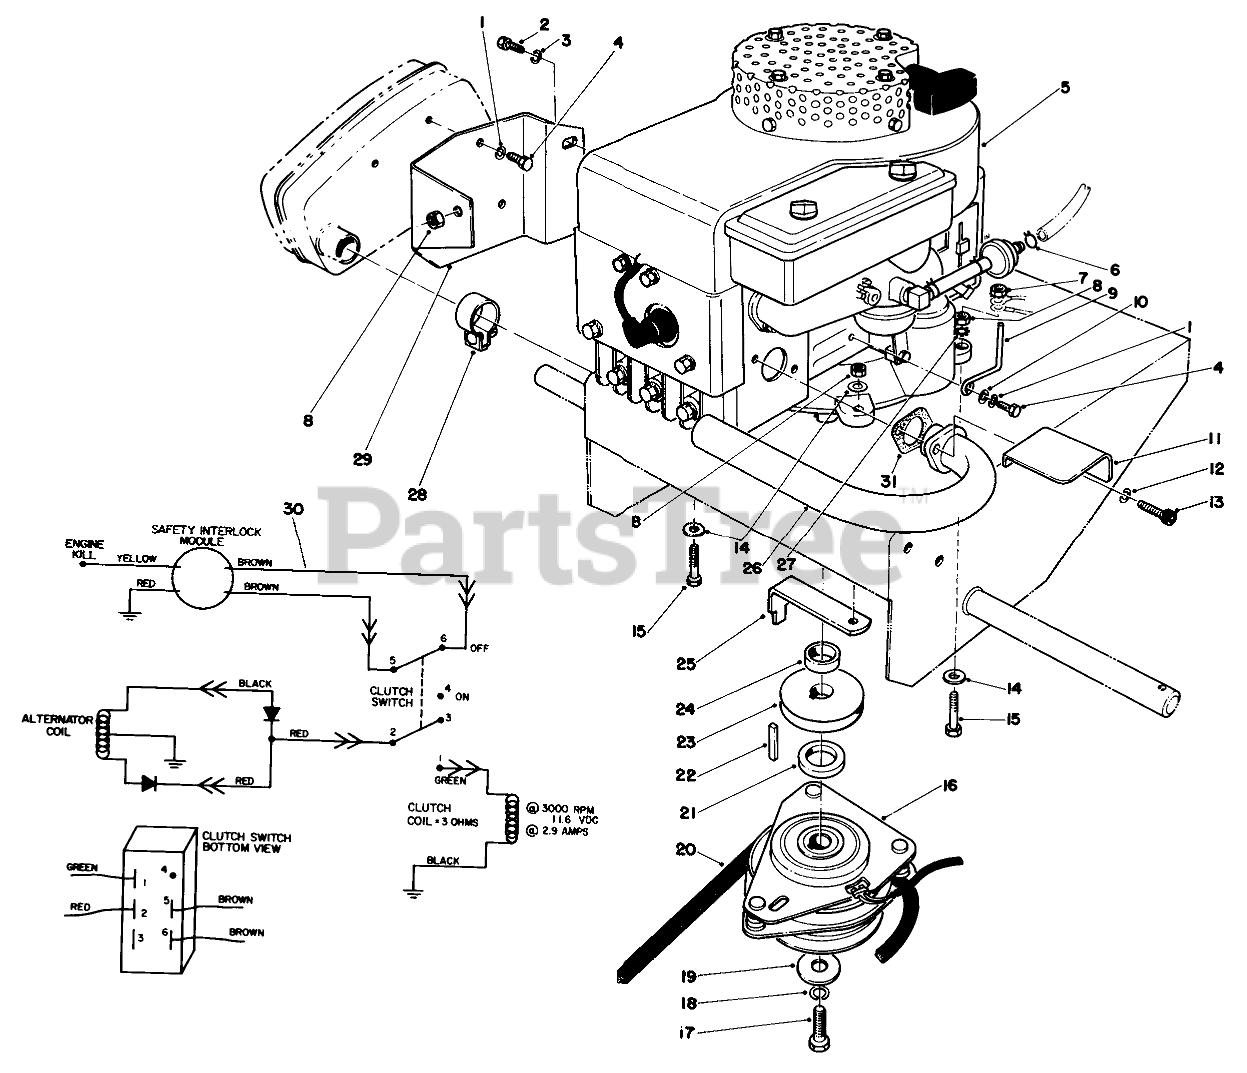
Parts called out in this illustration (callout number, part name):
1	WASHER-LOCK
2	SCREW-HH
3	WASHER-LOCK
4	SCREW-HH
5	Engine 12 H.P.
6	CLAMP-HOSE
7	NUT-KEPS
8	NUT-LOCK, CONE
9	BRUSH GUARD
10	WASHER-FLAT
11	HEAT SHIELD
12	WASHER-LOCK
13	SCREW-HSH
14	WASHER-PLAIN
15	SCREW-HH
16	CLUTCH/BRAKE
17	SCREW-HH
18	WASHER-LOCK
19	WASHER-CLUTCH
20	V-BELT, DRIVE
21	SPACER-LOWER
22	KEY-SQUARE
23	Pulley-Drive
24	Spacer-Upper
25	Retainer-Clutch
26	EXHAUST PIPE WA
27	WASHER-LOCK
28	MUFFLER CLAMP
29	MUFFLER BRKT B
30	WIRE HARNESS
31	Gasket
